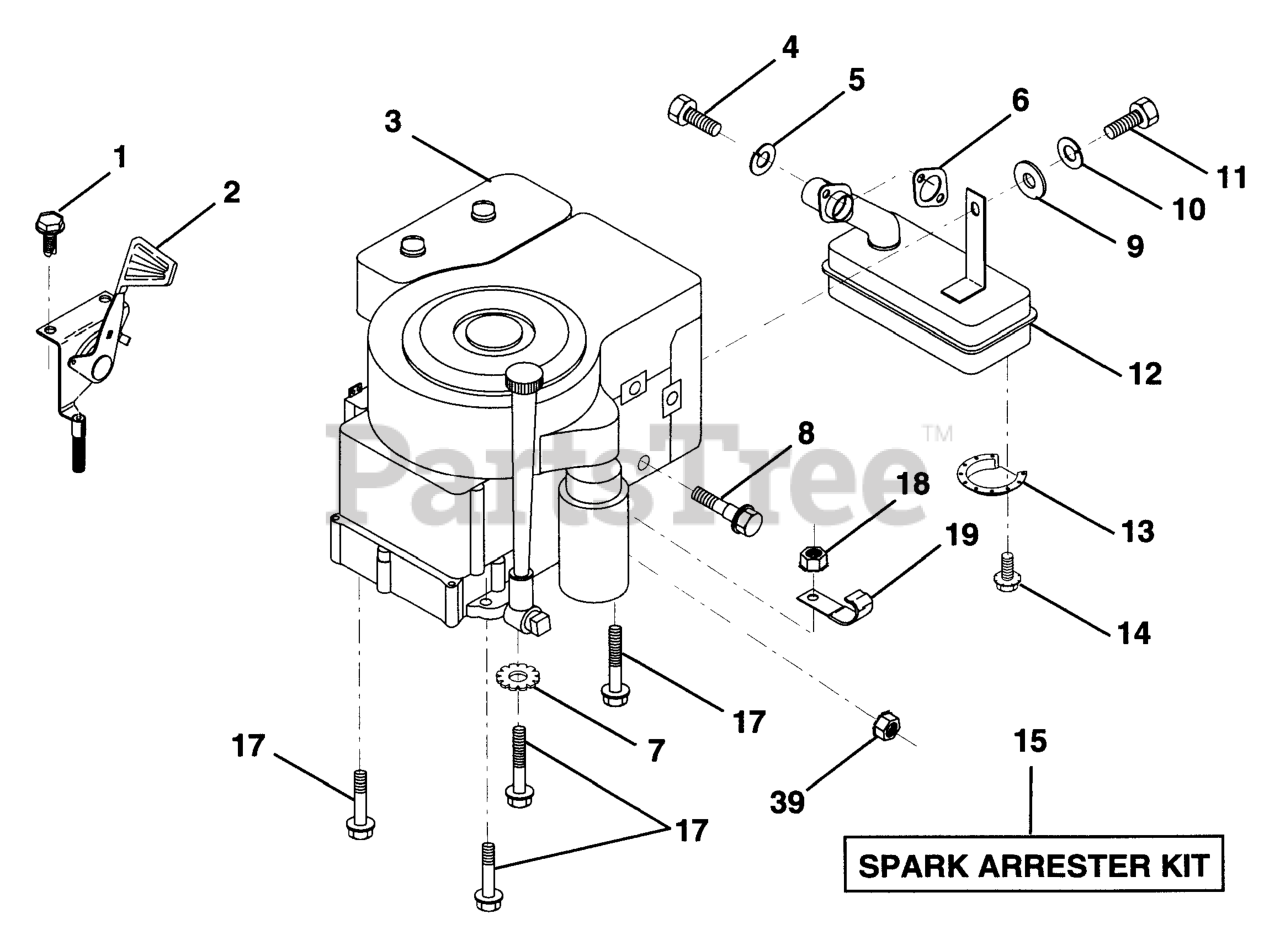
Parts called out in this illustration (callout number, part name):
2	CONTROL.TH/CH.RH.BLK.FLG.26
4	SCREW
5	WASHER.LOCK.HVY.HLCL.SPR.5/16
6	GASKET ENGINE
7	LOCKWASHER
9	WASHER
10	LOCKWASHER
11	Bolt, Hex, Fin.
12	MUFFLER.SINGLE.B&S.12HP
13	DEFL MUFFLER LTV
14	SCREW
15	KIT.SPARK ARRESTOR 794945 B&S
17	SCREW LT
19	CLIP T
30	NUT
